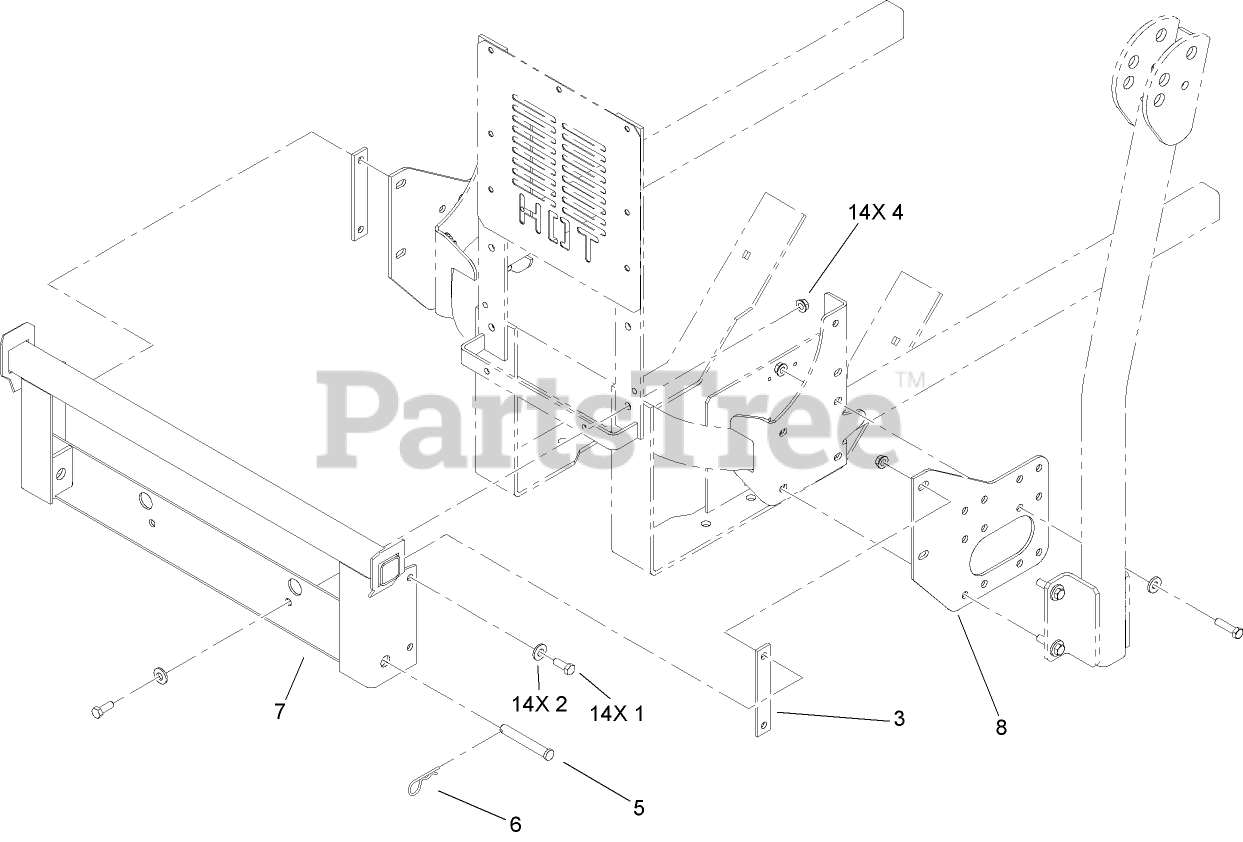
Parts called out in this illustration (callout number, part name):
1	SCREW-HH
2	WASHER-BELLEVILLE
4	NUT-HHF, WHIZ
5	PIN-CLEVIS
6	PIN-COTTER
7	MOUNT-BAGGER
8	PLATE-MOUNT, BAGGER
